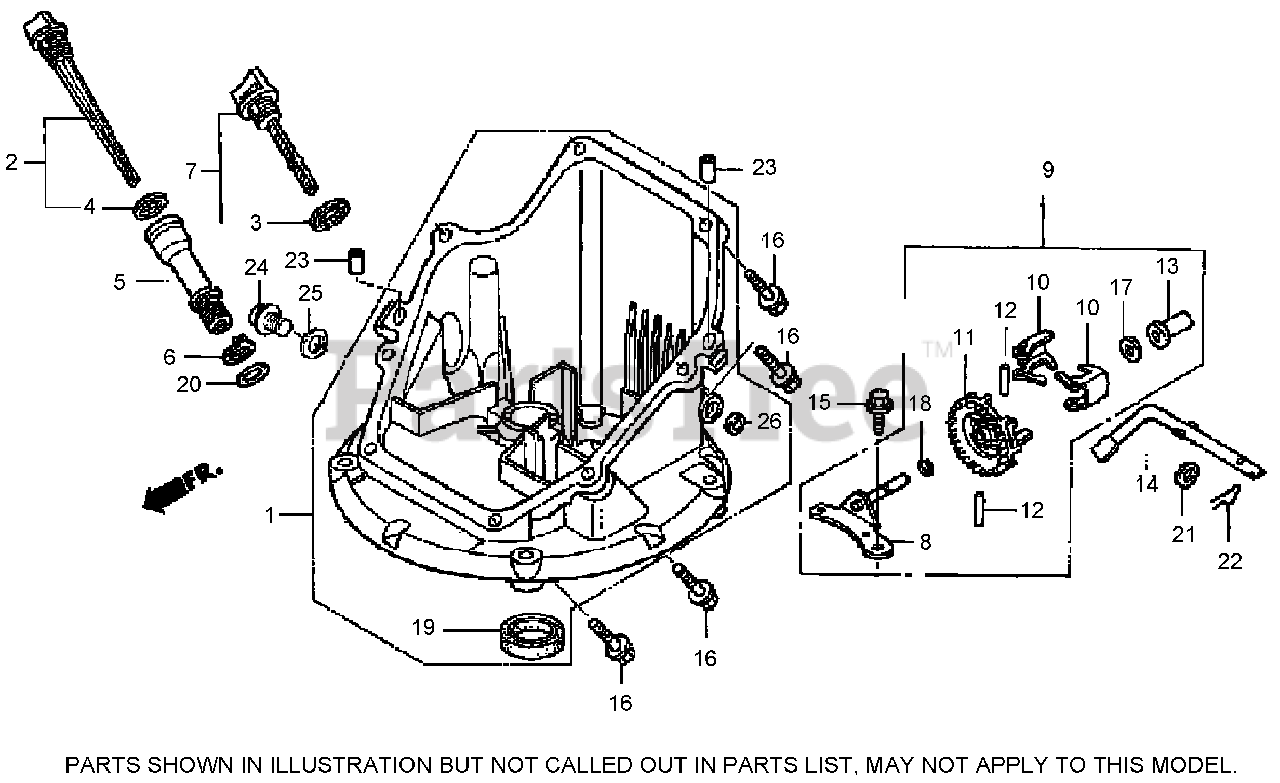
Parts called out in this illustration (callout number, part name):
1	PAN ASM., OIL
2	GAUGE ASM., OIL LEVEL
4	GASKET, OIL FILLER CAP
5	EXTENSION, OIL FILLER
6	WASHER, EXTENSION LOCK
8	SHAFT, GOVERNOR HOLDER
9	GOVERNOR ASM.
10	WEIGHT, GOVERNOR
11	HOLDER, GOVERNOR WEIGHT
12	PIN-GOVERNOR WEIGHT
13	SLIDER-GOVERNOR
14	SHAFT, GOVERNOR ARM
15	BOLT-FLANGE (6X14)
16	BOLT, FLANGE (6X25)
17	WASHER-THRUST (6MM)
18	CLIP-GOVERNOR HOLDER
19	OIL SEAL (28X41.25X6)
21	WASHER-PLAIN (6MM)
22	PIN-LOCK (8MM)
23	PIN, DOWEL (8X20)
